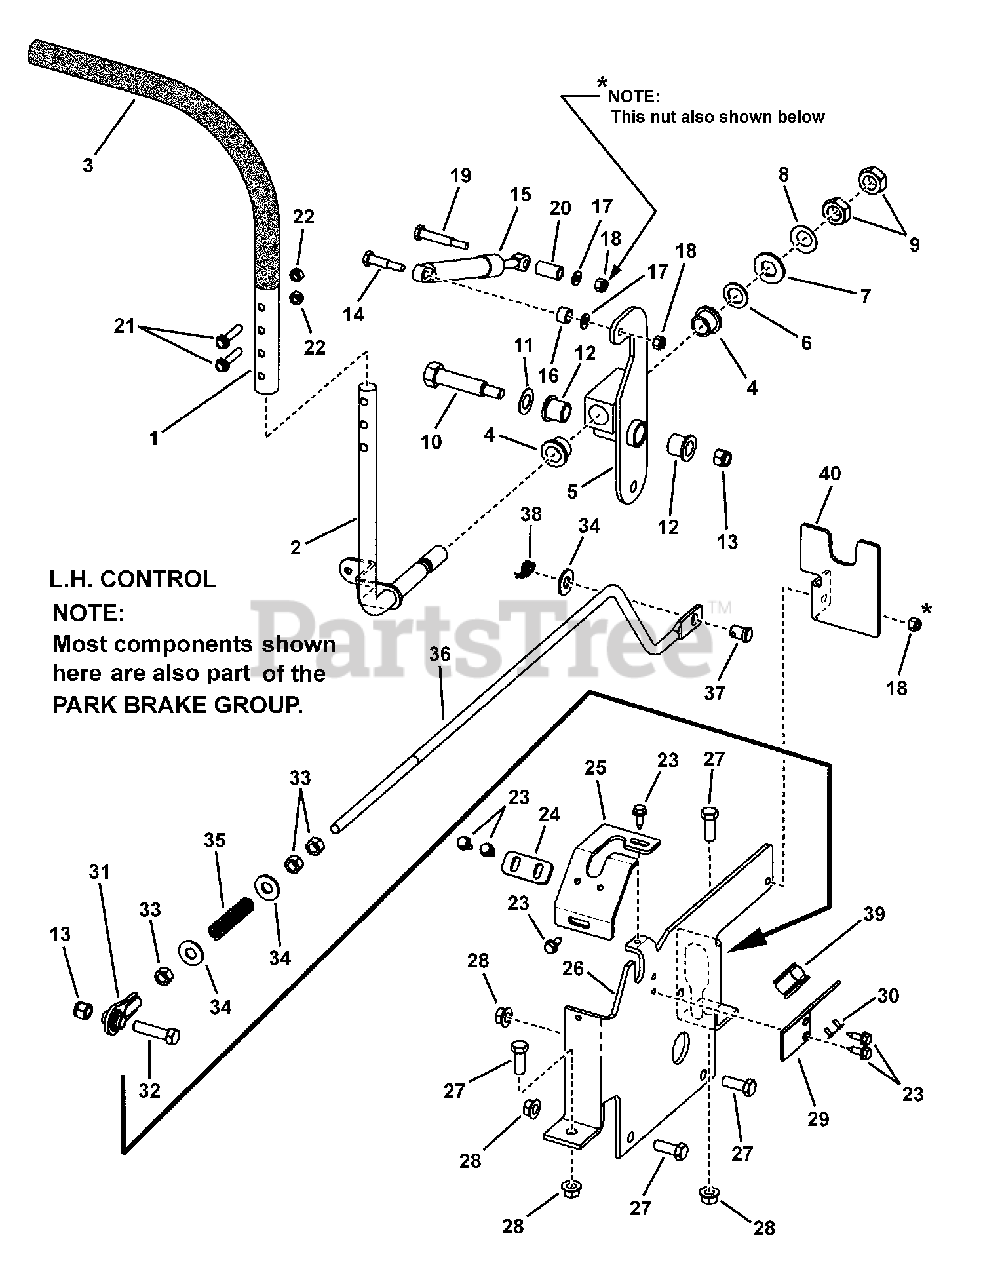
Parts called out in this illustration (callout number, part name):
1	HANDLE
2	WELDMENT, LH Control Arm
3	FOAM GRIP, Handle
4	BUSHING
5	WELDMENT, Control Bracket, LH
6	WASHER, 5/8 ID x 1.00 OD x .065 Nylon
7	WASHER, 5/8" Flat SAE
8	WASHER, .64 x 1.12 x .028 Beveled
9	NUT, 5/8-18 Hex Jam
10	SHOULDER BOLT, 3/8-16
11	THRUST WASHER, .562 ID x 1.000 OD x .030/.032 Thick
12	FLANGE BEARING, 9/16 I.D. P.M.
13	NUT, 3/8-16 Hex Nyloc
14	SHOULDER BOLT, 5/16 x 1/4-20
15	DAMPENER, Hydraulic
16	SPACER, 9/16 OD x 12GA x .325
17	WASHER, 1/4" I.D. Flat
18	NUT, 1/4-20 Hex Nyloc
19	SHOULDER BOLT, 5/16 x 1/4-20
20	SPACER, 9/16 OD x 12GA x .899
21	SCREW, 1/4-20 x1-1/4" Hex Head Cap, GR 5
22	NUT 1/4-20 Hex Center Lock, GR 5 YZ
23	SCREW, 1/4-20 x 3/4" Hex Washer Self-Tap
24	PLATE, Fwd/Rev Adjust
25	TRACK, Control Stick L.H.
26	CONTROL BRACKET, LH
27	SCREW, 3/8-16 x 1" Hex Head Cap, GR 5, YZ
28	NUT, 3/8-16 Hex Flange Lock
29	BRACKET, Rod Holder, RZT
30	POP RIVET, 1/8 x 3/8"
31	ROD END
32	SCREW, 3/8-16 x 1-1/2" Hex Head Cap, GR 5
33	NUT, 3/8-24 Hex, GR B, YZ
34	WASHER, 7/16" Flat
35	SPRING, Compression (Brake)
36	ROD, Link Fwd./Rev. (3/8-24 thread)
37	CLEVIS PIN, 7/16 x 1"
38	COTTER PIN, 1/2 Self Locking, YZ
39	CLIP, Spring
40	BRACKET, Fender Support, LH RZT
